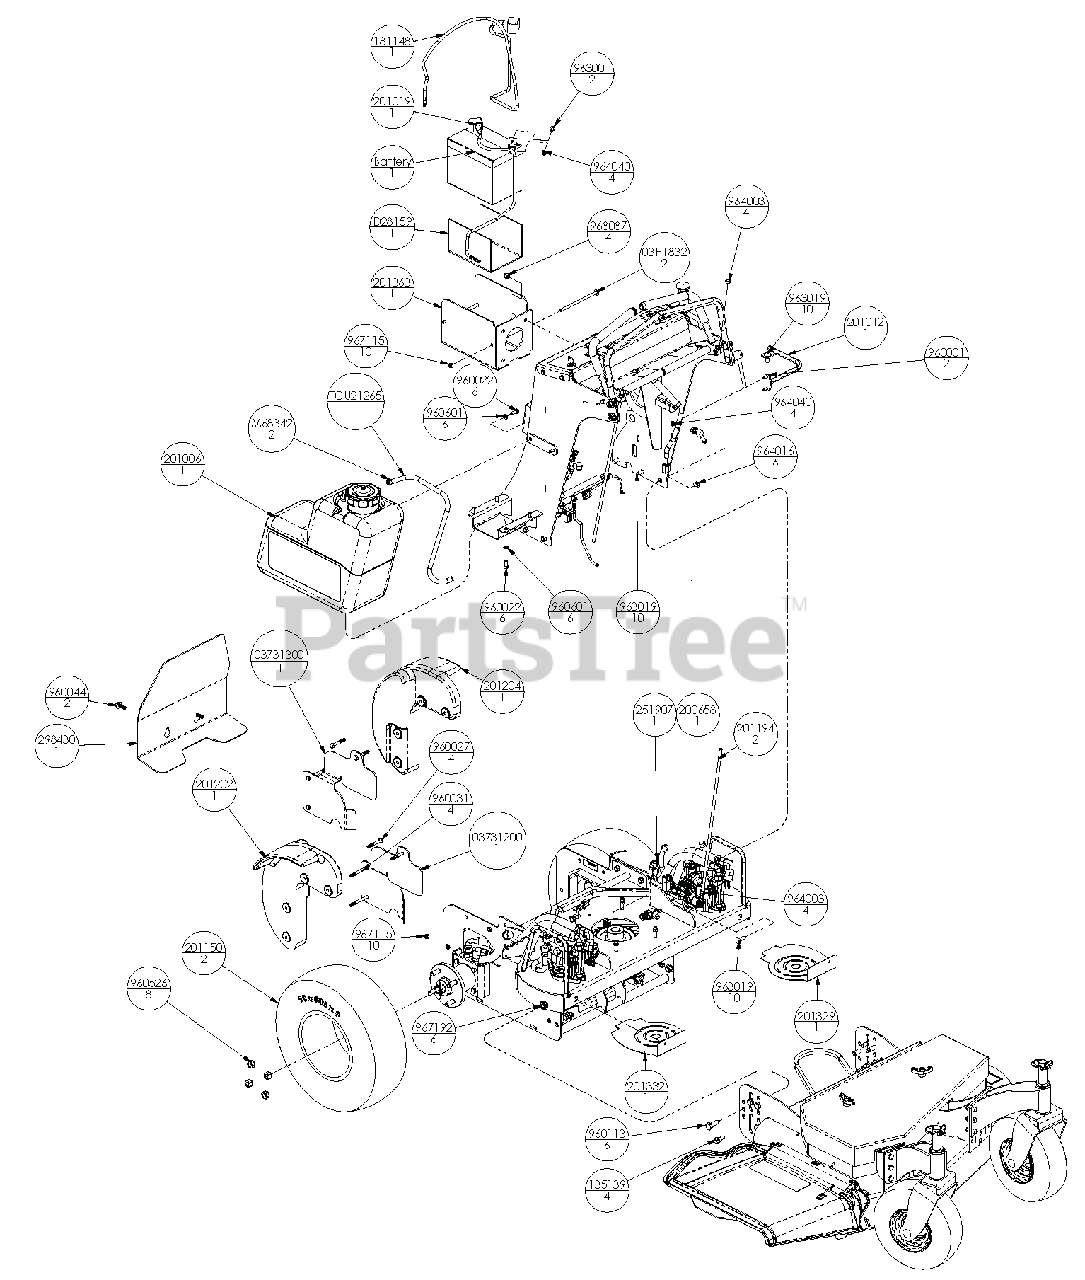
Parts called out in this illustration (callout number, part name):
1	STRIP, RUBBER
2	CLAMP, HOSE (RED) #
3	HOSE, 1/4" ID LOW PERM FUEL 50
4	BOLT, 5/16X6 LONG NK RD HD D-Z
5	BOLT, 1/2X1.06X3/8-16 SLD 5 Y
6	CABLE, BATTERY STARTER 48"
7	BATTERY, 12V-U1-CCA270MIN
8	PIN, CVS SPG 3/8" YOKE SPEC Y
9	TANK, FUEL SCORPION ASSEMBLY
10	WLDMT, RESERVOIR GUARD
11	CABLE, BATTERY GROUND, 25"
12	CONSLE BTRY BRKT W/DCAL EVRIDE
13	SHIELD, LH PUMP EVERRIDE
14	SHIELD, RH PUMP EVERRIDE
15	SHIELD, RH MOTOR W/DECAL
16	SHIELD, LH MOTOR W/DECAL
17	ASSY, TIRE/WHL 18-6.50-8
18	SHIELD, ENGINE W/DECALS EVRIDE
19	ROD, CONTROL 5/16-24 X 22.75
20	RH CAST WEIGHT MACHINED
21	LH CAST WEIGHT MACHINED
22	YOKE, 3/8-24 RH ADJUSTABLE
23	BOLT, 1/4-20X.750 HEX 5 Y
24	BOLT, 5/16-18X.750 HEX 5 Y
25	BOLT, 5/16-18X2.00 HEX 5 Y
26	BOLT, 5/16-18X3.00 HEX 5 Y
27	BOLT, 3/8-16X1.00 FGH 8 Y
28	BOLT, 1/2-13X1.25 HEX 5 Y
29	NUT, 1/2-20 LUG C
30	WASHER, .313 MED SPRG LOCK Y
31	BOLT, 1/4-20 X .625 WSH Y
32	BOLT, 3/8-16X1.00 CRG 5 SN Y
33	NUT, 5/16-24 STD HEX GR5 Y
34	LOCKNUT, 3/8-16 WHIZ Y
35	LOCKNUT, 1/4-20 WHIZ Y
36	LOCKNUT, 5/16-18 NYLOC Y
37	LOCKNUT, 1/2-13 WHIZ GR5 Y
38	LOCKNUT, 3/8-16 NYLOC Y
